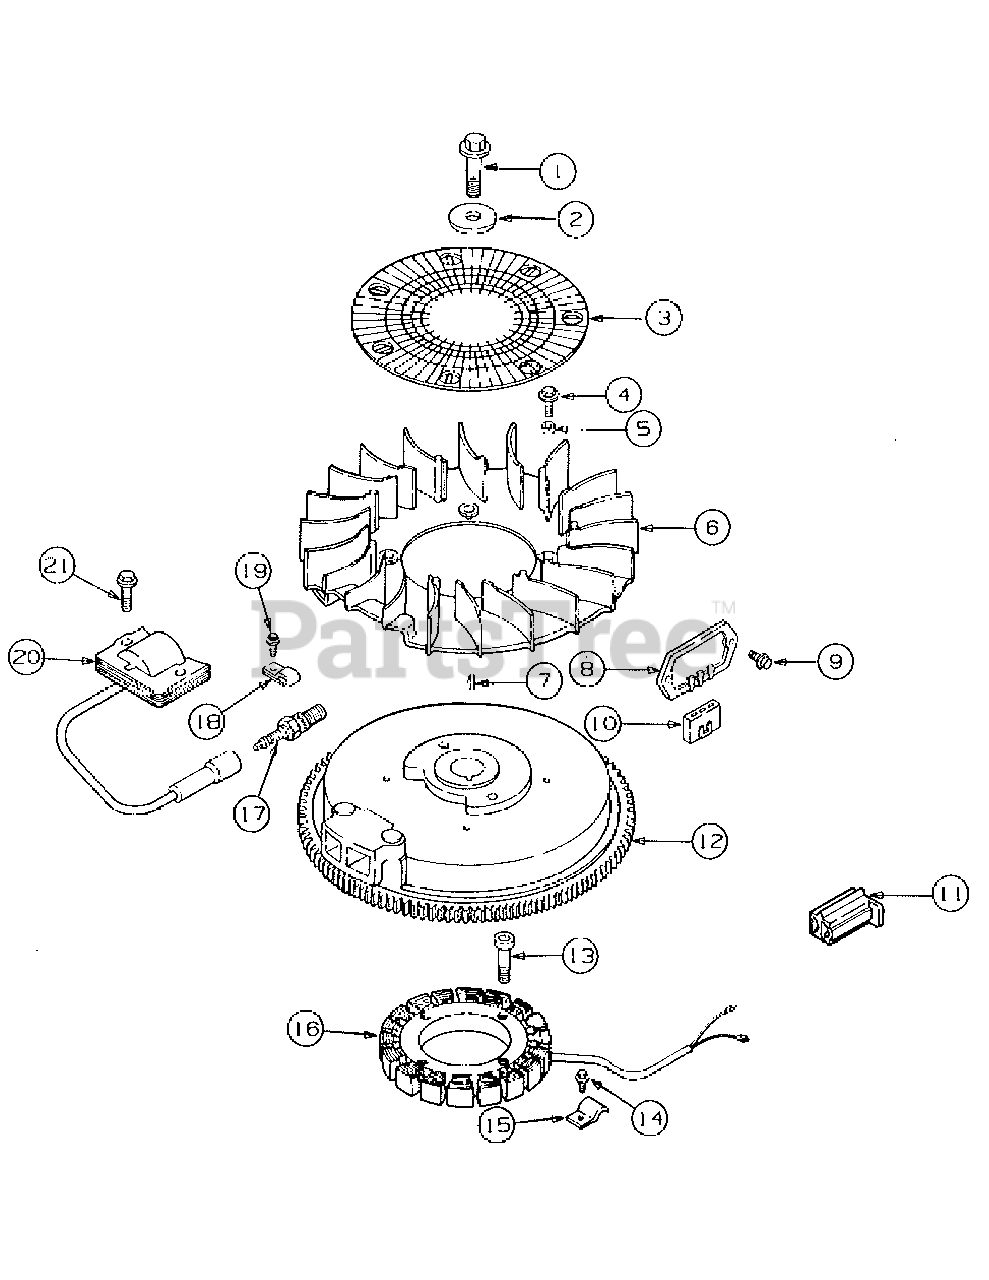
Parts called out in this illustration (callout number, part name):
1	Screw, Flywheel Mouting
2	Washer, Flywheel Screw
3	Screen, Grass
4	Screw, Fan Mounting
5	Spacer, Fan
6	Fan
8	Rectifier,Unregulated
9	Screw, Retifier Mounting
10	Connector (3 Contact)
11	Connector (2 Contact)
12	Flywheel Ass'y
13	Screw, Stator Mounting
14	Screw, Wire Clip
15	Clip, Stator Wire
16	Stator
18	Clip, Kill Lead
19	Screw, Lead Clip
20	Module, Ignition
21	Screw, Ignition Module, M5 x 0.8 x 20
